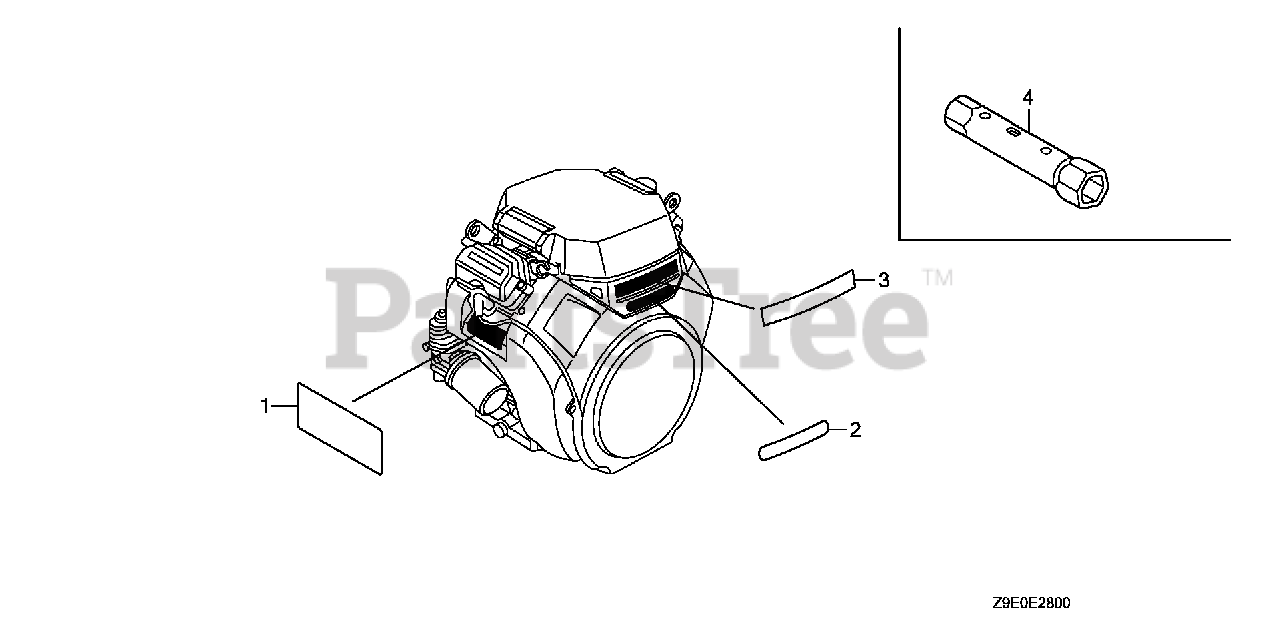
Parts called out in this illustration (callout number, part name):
1	MARK, OPERATOR CAUTION (ENGLISH)(MADE IN JAPAN)
2	EMBLEM (GX630)
3	MARK, HONDA
